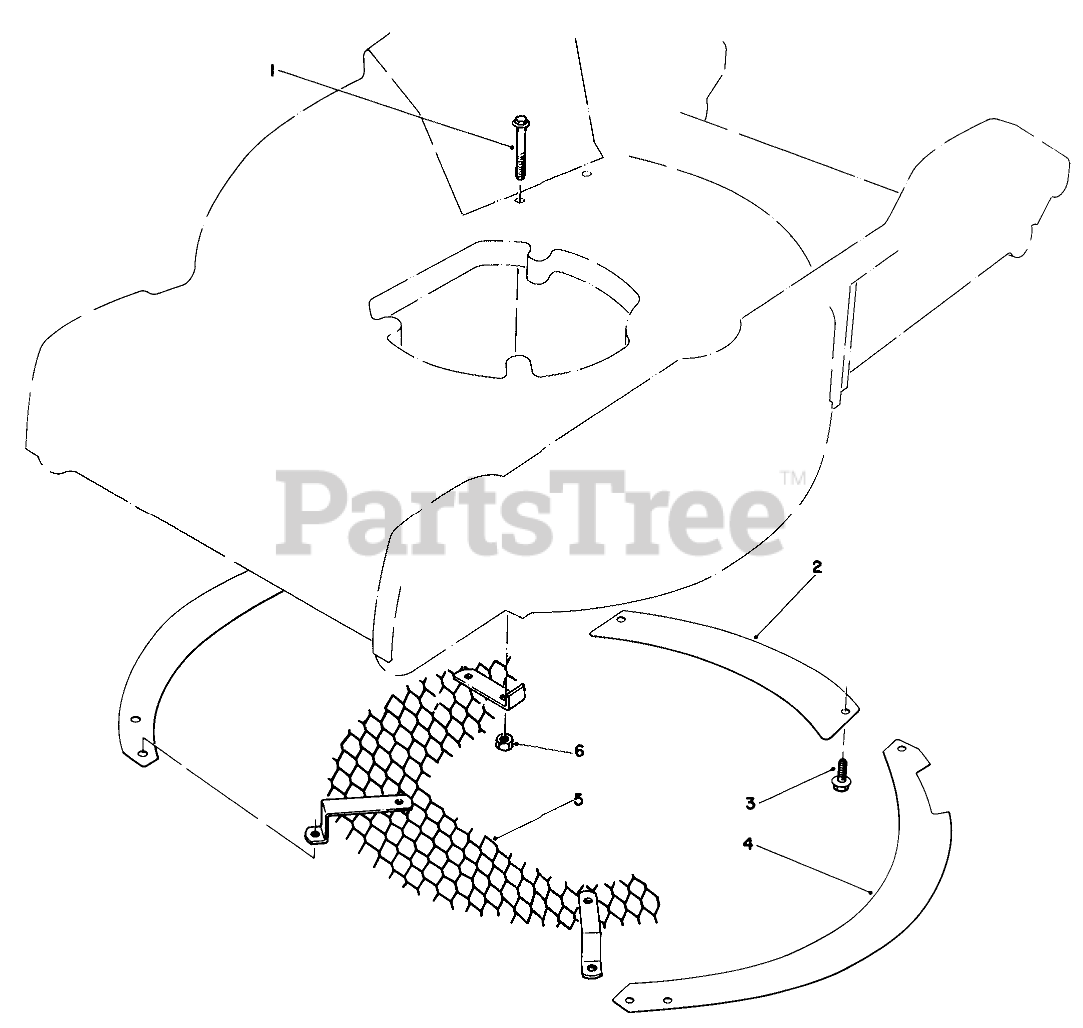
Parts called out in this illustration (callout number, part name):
1	Screw
2	Rear Baffle
3	SCREW
4	Outer Baffle
5	Screen
6	NUT-LOCK
